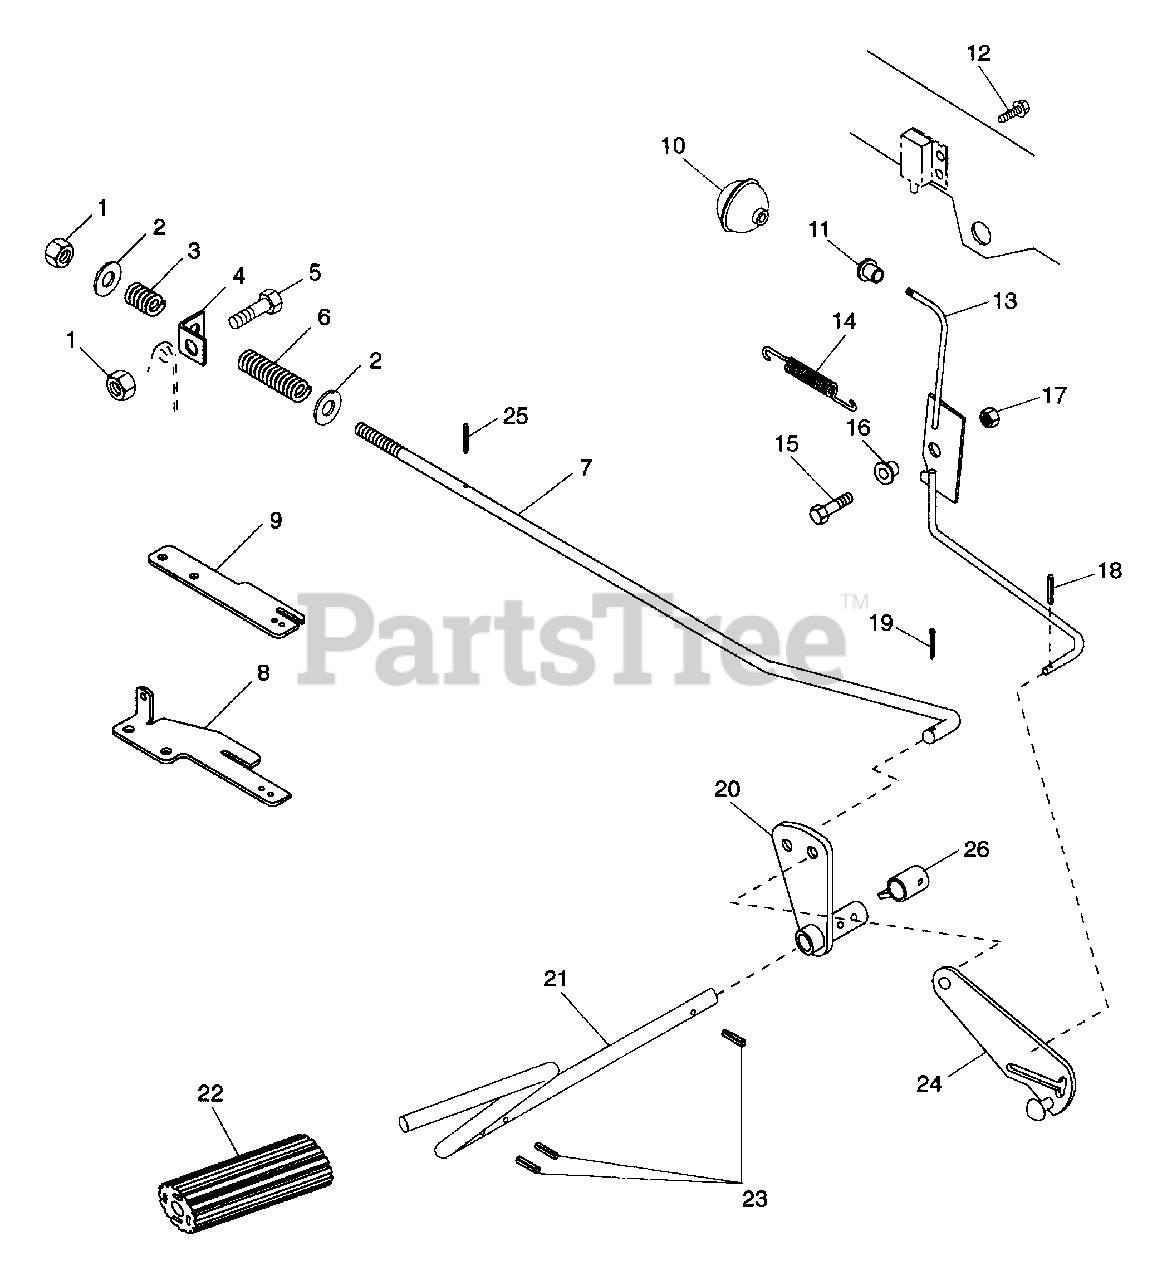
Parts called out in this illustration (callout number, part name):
1	NUT-LK-CTR .375-16 GR A PL
2	WSHR-FL-STL.406X.812X.065PL
3	SG-COMP .125X.78X1.00 YWZ
4	BRACKET
5	BLT-HEX .38-16X.75 PL GR5
6	SG-COMP .048X.59X2.06 WLD9
7	ROD- BRAKE (5SPD)
8	BRAKE GUIDE
9	BRAKE GUIDE
10	PUSH/PULL CONTROL KNOB
11	SNAP BUSHING-.437
12	SCR-TAP 12-24X.50 HWH PL TR
13	LEVER, PARKING BRAKE
14	SG-TENS .051X.44X4.38 WLD 7.5
15	BLT-HEX .31-18X.75 PL GR5
16	BSHG, FLG .325X.499X.26X.88
17	NUT-LK .312-18 GR A PL
18	PIN-ROLL .093X.50
19	PIN-COTR .09X.75 PL
20	ARM & HUB
22	COVER- PEDAL
23	PIN-GRV .188X1.25 TP A
24	PLATE, PIVOT
25	PIN-ROLL .125X.75
26	LEVER - BRAKE SWITCH
